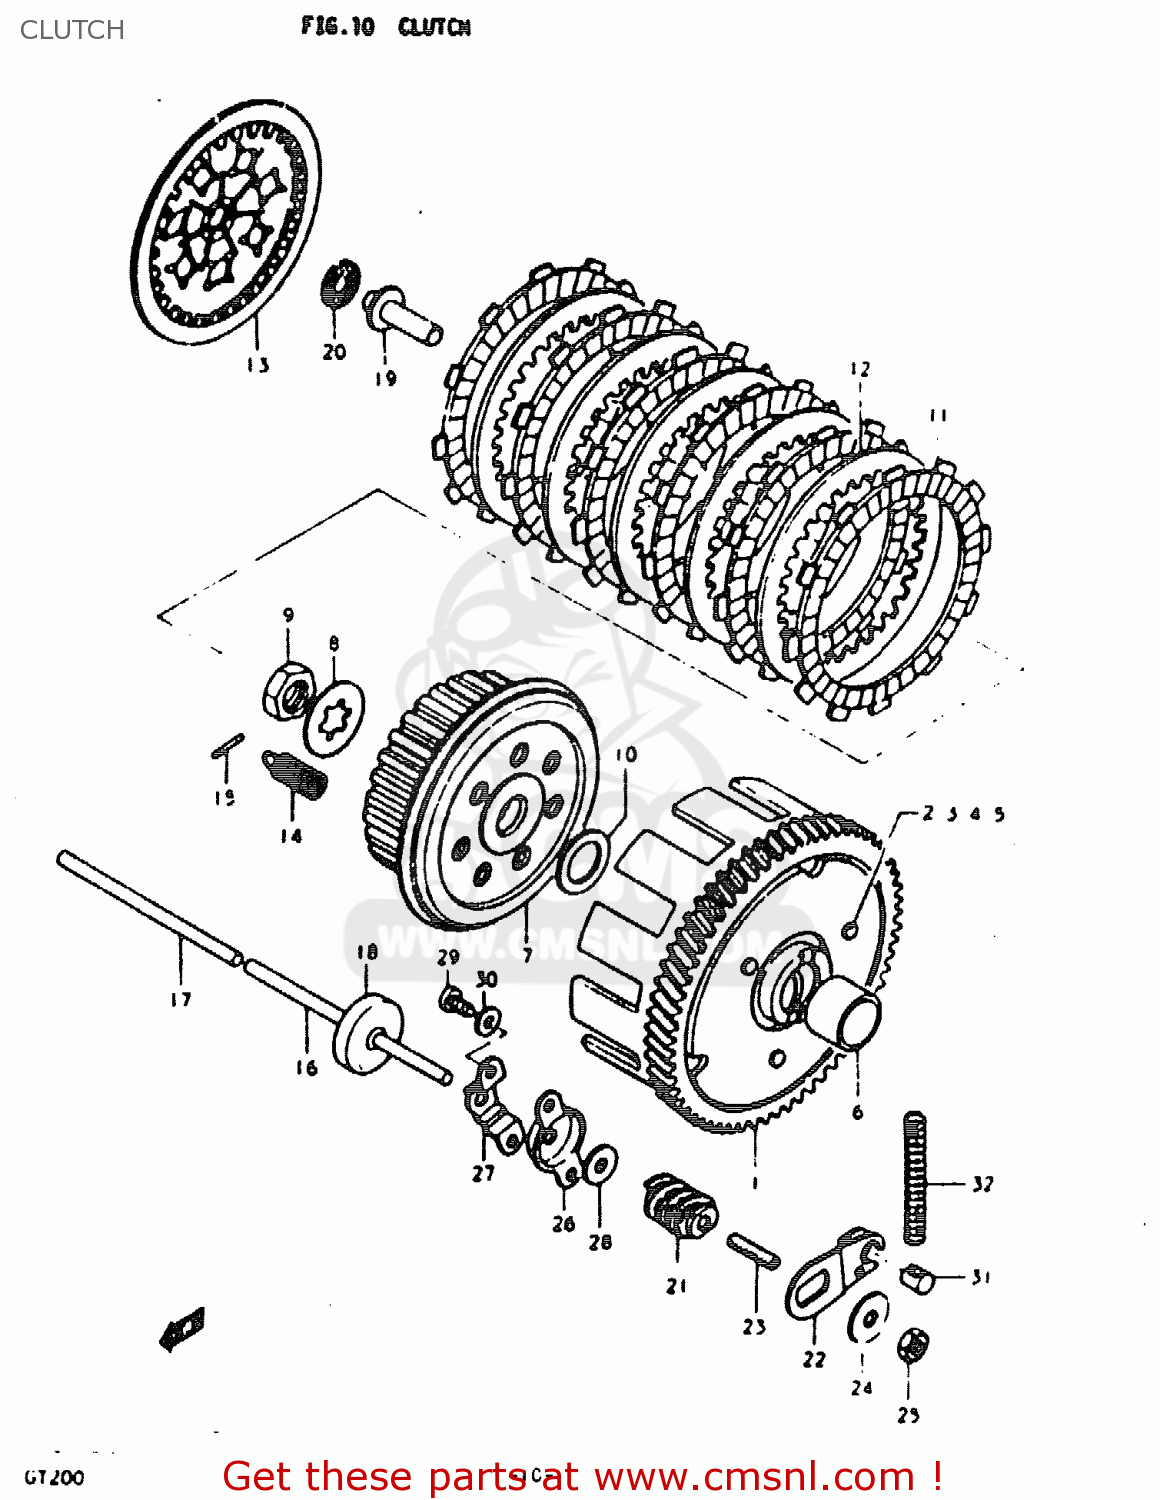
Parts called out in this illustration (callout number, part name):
1	GEAR ASSY, PRIMARY DRIVEN
2	DAMPER,PRIMARY DRIVEN
3	DAMPER, NO.2
4	PLATE
5	RIVET
6	SPACER
7	HUB,CLUTCH SLEEVE
8	WASHER,LOCK
9	NUT
10	WASHER
11	PLATE,CLUTCH DRIVE
12	PLATE,CLUTCH DRIVEN (NAS)
13	PLATE,CLUTCH PRESSURE
14	SPRING
15	PIN(2.5X19.8)
16	ROD,CLUTCH PUSH
17	ROD,CLUTCH PUSH NO.2
18	SEAL,OIL(6X30X7)
19	PIECE, PUSH
20	BEARING(10X22X2.8)
21	SCREW,CLUTCH RELEASE
22	ARM,CLUTCH RELEASE
23	SCREW
24	WASHER
25	NUT 6MM
26	COVER
27	HOLDER,DUST SEAL
28	SEAL,DUST(5.3X13X5)
29	SCREW
30	WASHER
31	PIECE,RELEASE ARM END
32	SPRING
